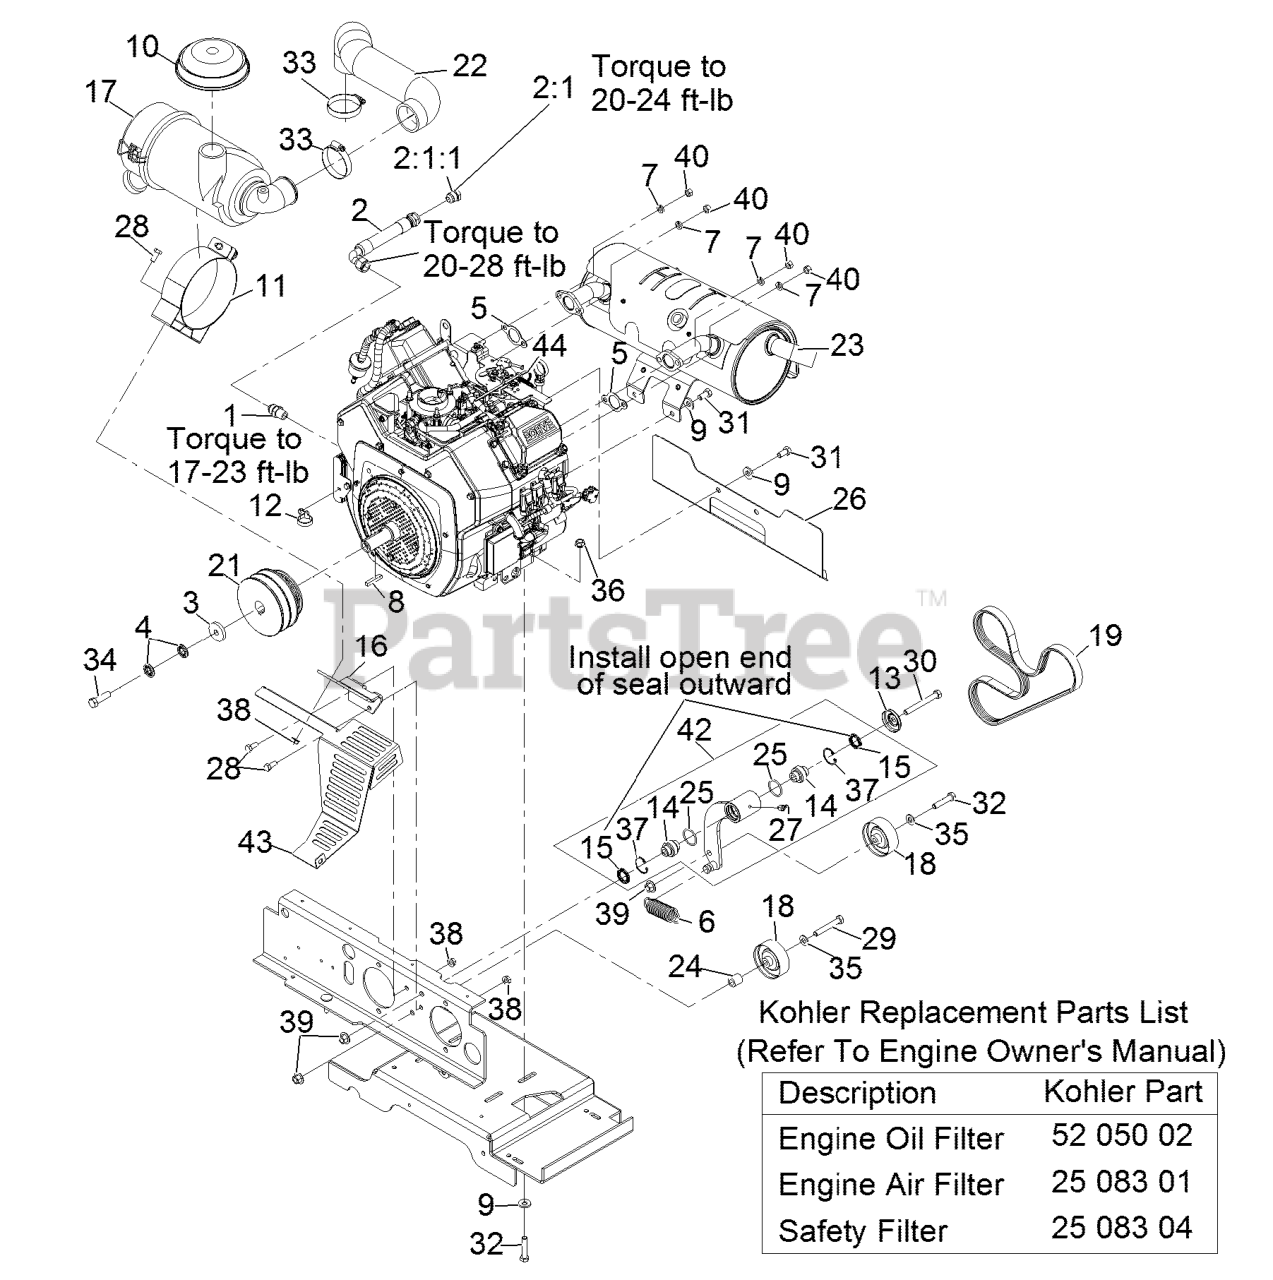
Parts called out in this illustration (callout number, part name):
1	FITTING-STRAIGHT
2	OIL DRAIN HOSE ASM
2:1	PLUG-HH
2:1:1	O-RING
3	WASHER-CLUTCH
4	WASHER-SPRING
6	SPRING-IDLER
7	WASHER-LOCK
8	KEY-SQUARE
9	WASHER-BELLEVILLE
10	HOOD-CLEANER, 2" AIR INTA
11	BRACKET-FILTER, AIR
12	Tie-Cable
13	GUARD-TOP
14	BEARING-SPHERICAL
15	SEAL-LIP, SINGLE
16	BRACKET-FILTER, AIR
17	AIR CLEANER CANISTER ASM
19	BELT-V
22	HOSE-EFI AIR INTAKE
23	MUFFLER
24	SPACER-MOUNTING, STEERING
26	SHIELD-EXHAUST
27	FITTING-LUBE, 45 DEG
28	SCREW-HH
29	BOLT-CARR
30	SCREW-HH
31	SCREW-HH
32	SCREW-HH
33	CLAMP-HOSE
34	SCREW-HH
35	WASHER-FLAT
36	NUT-HHF, WHIZ
37	RING-SNAP
39	NUT-FLANGE
40	NUT-HEX
42	IDLER ASM
43	SHIELD-HEAT
44	TIE-PLASTIC
